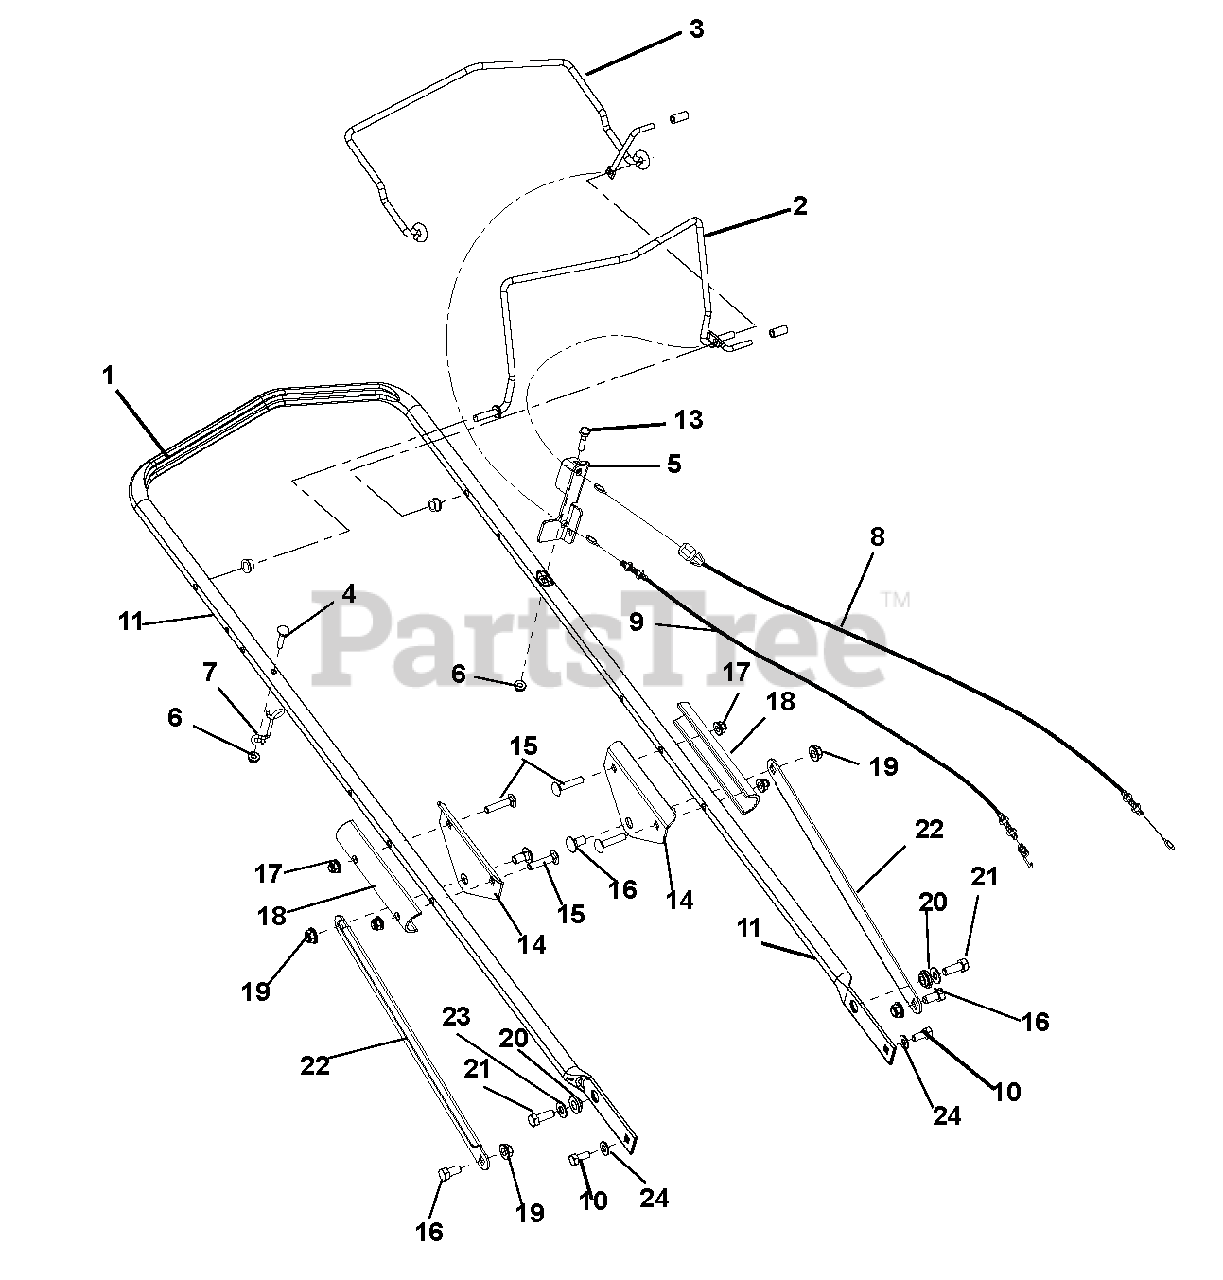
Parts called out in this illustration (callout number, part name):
1	HANDLEBAR,PRO 21
2	BAIL, OPERATOR PRESENCE
3	BAIL, CLUTCH
4	BLT-RDHDXLSQNK.25-20X1.25 G5ZC
5	ANCHOR, CABLE - THUMB ADJUST
6	@NUT-LK-TOP-FLG .25-20 YWZC
7	GUIDE - PULLCORD
8	CABLE, TO BE REPLACED 12925
9	CABLE, XD DOUBLE BAIL DRIVE
10	@BLT-HEX .31-18X.75 GR5 YWZC
11	CONDUIT CLIP
12	PLATE,HINGE
13	@BLT-HEX .25-20X1.25 GR5 YWZC
14	PLATE,HANDLEBAR
15	@BLT-RDHDSQNK .31-18X1.50 G5YZ
16	@BLT-HEX .38-16X.75 GR5 YWZC
17	@NUT-LK-NYL-FLG .31-18 YWZC
18	SERVICE BAR BRACE
19	@NUT-LK-NYL-FLG .38-16 YWZC
20	BSHG-FLG .406X.88X.270X.140
21	@BLT-HEX .38-16X1.00 GR5 YWZC
22	STRAP,HANDLEBAR
23	@WSHR-FL-STL.406X.812X.065 YWZ
24	@WSHR-FL-STL.344X.688X.065YWZC
